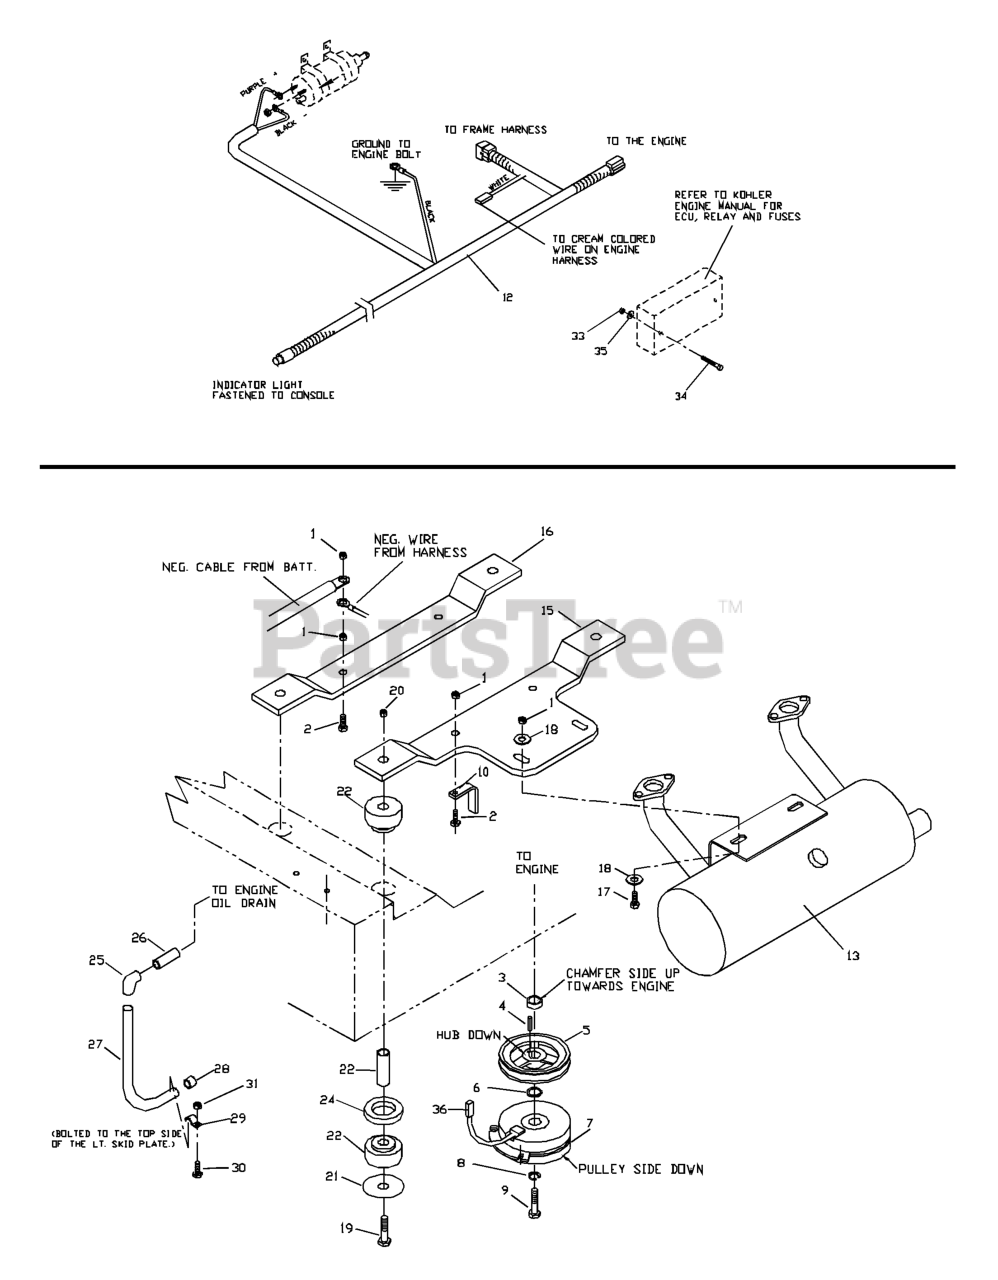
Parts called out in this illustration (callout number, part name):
1	NUT 5/16C CENTERLOCK
2	HCS 5/16C X 1 3/4
3	SPACER .70"
4	KEY 1/4 SQ X 1.0
6	SPACER .508"
7	ELECTRIC CLUTCH W/CABLE
8	7/16 LOCKWASHER
9	BOLT 7/16F X 2 1/2
10	CLUTCH TIE DOWN
12	WIRE HARNESS - EFI
13	MUFFLER EFI KOHLER GEN II
15	REAR ENGINE MOUNT
16	ENGINE MOUNT
17	HCS 5/16C X 1
18	WASHER 5/16 FLAT
19	HCS 1/2C X 3 1/4
20	NUT 1/2-13 HEX NYLOC ZD
21	ISOLATOR WASHER
24	ISOLATOR SPACER
25	90 DEG.ELBOW 3/8NPT
26	PIPE 3/8 NPT 1-1/2
27	OIL DRAIN HOSE
30	HCS 1/4C X 3/4 HCS
31	NUT 1/4C CENTER LOCK
32	SCREW #10 X 1/2 SELF TAPPING
33	NUT 10-24 NYLOC
34	BOLT 10-24 X 2
35	WASHER #10
36	CLUTCH HARNESS
